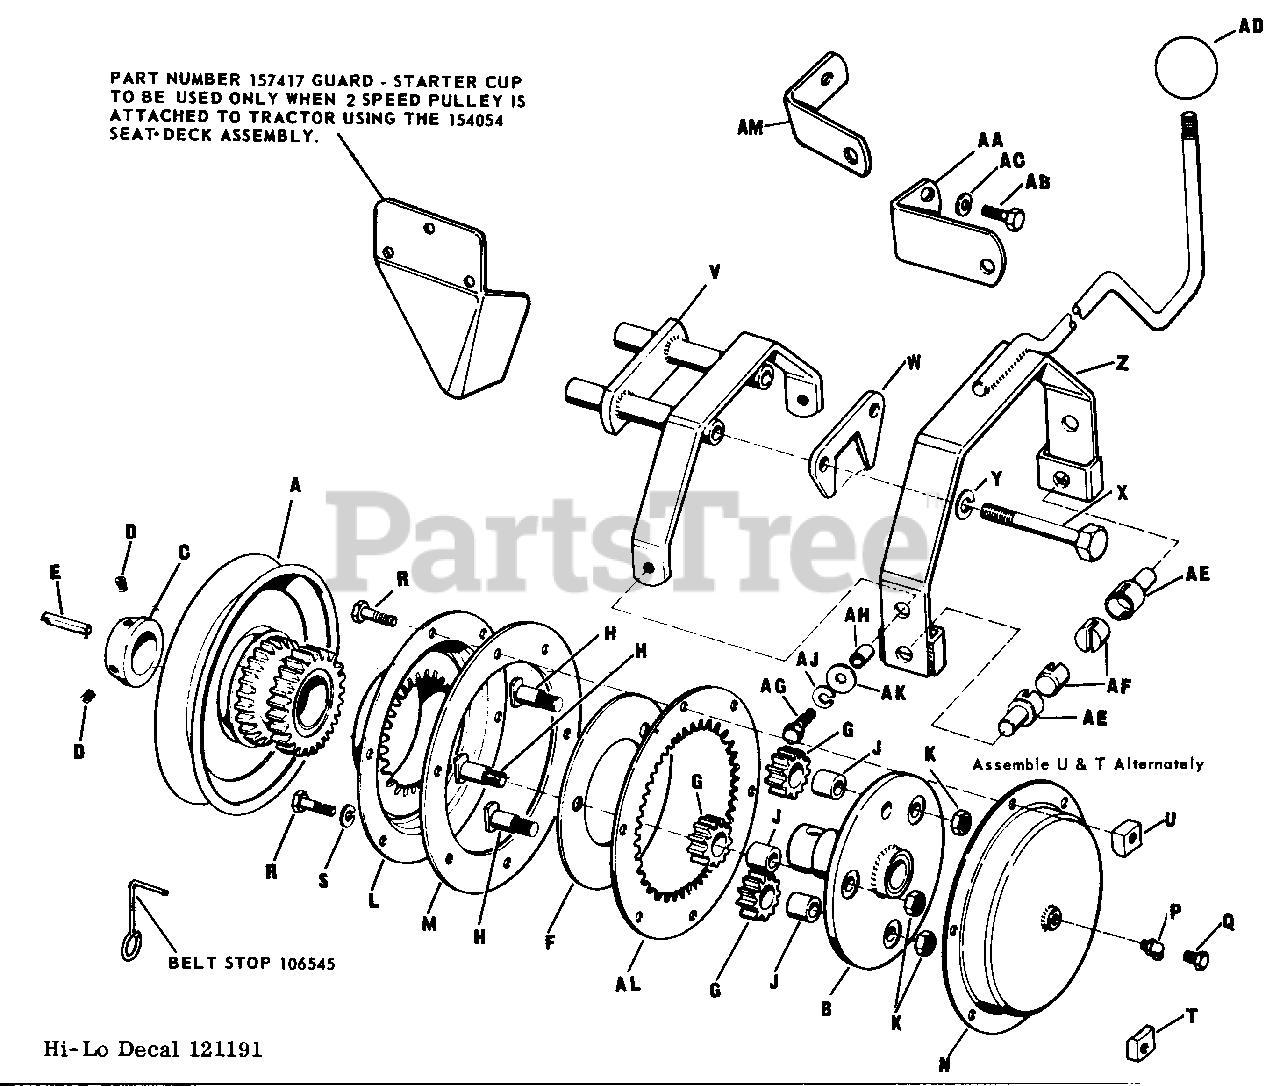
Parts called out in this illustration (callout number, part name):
A	Pulley & Gear Ass'y.
B	Spider & Brg. Ass'y.
C	Set Collar
D	Set Screw 5/16"-18 N.C. x 3/8"
F	Ring, Bolt
J	Needle Bearing
K	Full Lock Nut, Hex., 5/16"-18 N.C.
L	Cover Ass'y. L.H.
M	Shift Ring
N	Cover Ass'y R.H.
P	Grease Fitting
Q	Hex., Cap Screw 1/4"-28 N.F. x 1/2
R	Hex Cap Screw 5/16"-18 N.C. x 5/8"
S	Lock Washer 5/16"
T	Special Nut
U	Special Nut
V	Support Ass'y, Shift
Y	Lock Washer 5/16"
Z	Fork Ass'y. Shift
AA	Support, Shift Rod F/2010-12 & Earlier
AB	Hex. Cap Screw 1/4"-20 N.C. x 1"
AC	Lock Washer, 1/4"
AF	Bearing, Pivot
AG	Hex. Cap Screw 1/4"-20 N.C. x 3/4"
AJ	Lock Washer, 1/4"
AK	Washer Plain 1/4"
AL	Gear Ring.
AM	Support Shift Rod F/2110
